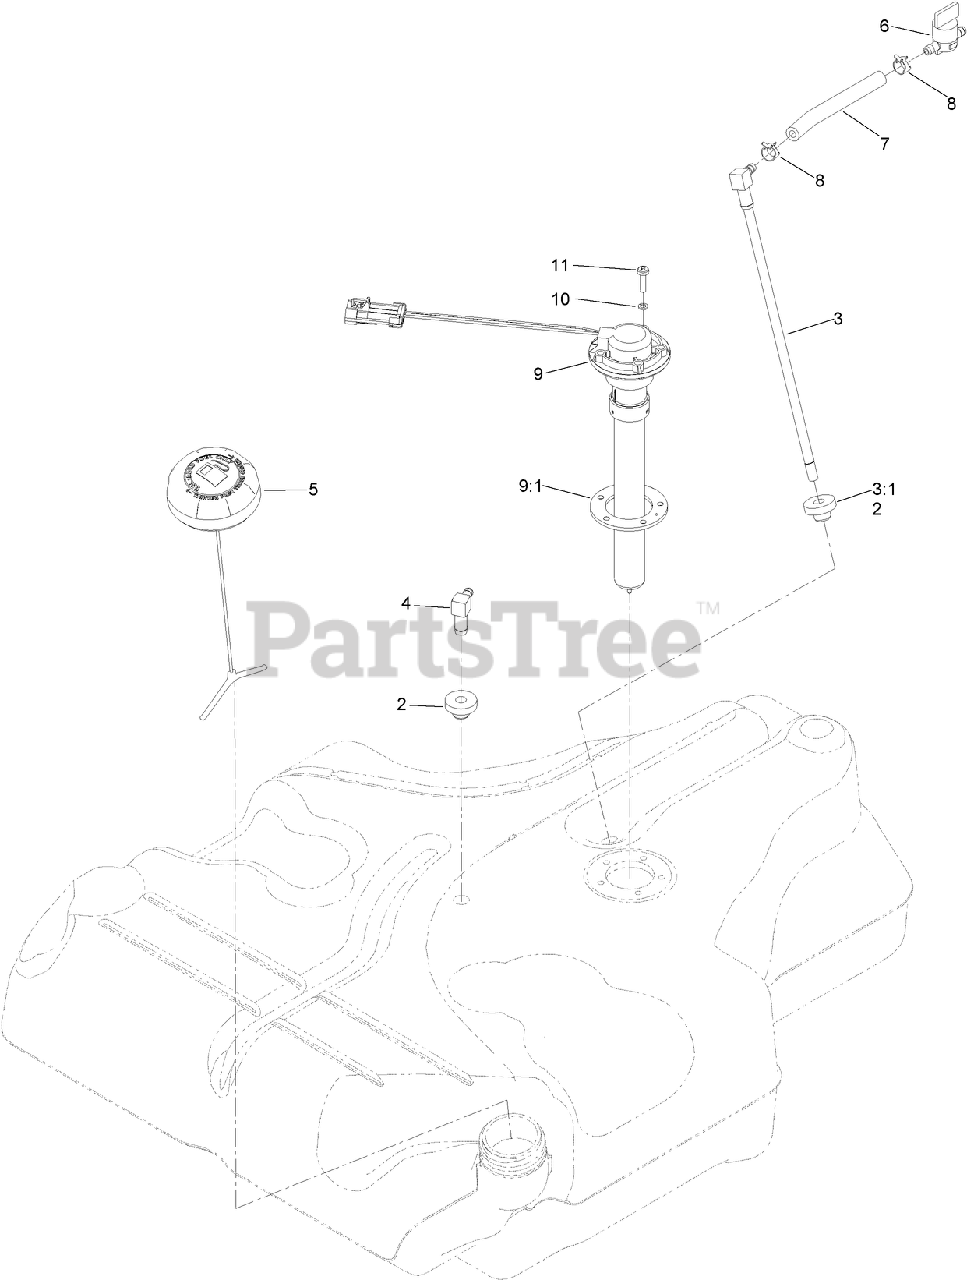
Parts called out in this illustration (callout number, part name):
2	BUSHING
3	FUEL LINE KIT (WITH GROMMET)
3:1	BUSHING
4	FITTING-90 ELBOW
5	CAP-FUEL, RATCHETING
6	VALVE-FUEL
7	HOSE-FUEL
8	CLAMP-HOSE
9	SENDER-FUEL
9:1	GASKET-SENDER, FUEL
10	WASHER-LOCK
11	SCREW-PAN
